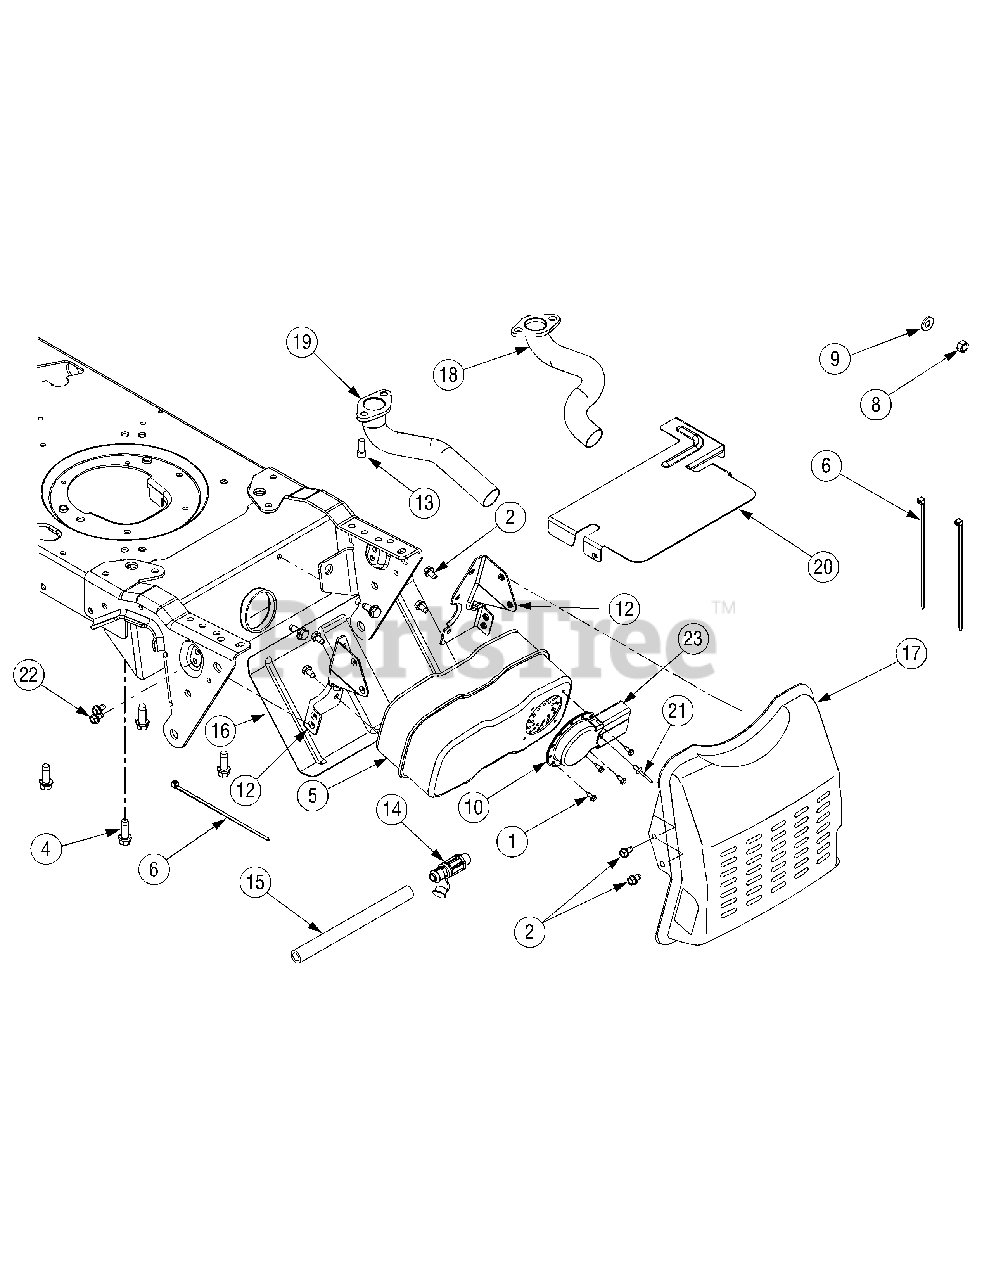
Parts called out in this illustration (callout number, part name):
1	Screw, #8-18, 0.500
2	Screw, Hex, 1/4-20, 0.500
3	Screw, Hex, 5/16-12 x .75
4	Screw, Hex, 3/8-16 x 1.25
5	Muffler, Dual Inlet
6	Cable, Tie, 3/16 x .05 x 7.4
7	Nut, Flange Lock, 5/16-18
8	Hex Flange Nut, 3/8-16
9	Lock Washer,.406 x.875 x.059
10	Deflector, Muffler
14	Drain, Oil
15	Extension Hose, Oil Drain
16	Heat Shield, Lower
17	Shield, Muffler
18	Pipe, Exhaust, LH
19	Pipe, Exhaust, RH
20	Heat Shield, Upper
21	Rivet, Pop, .188 x .325
22	Screw, Hex, 1/4-20, 0.750
23	Extension, Deflector
